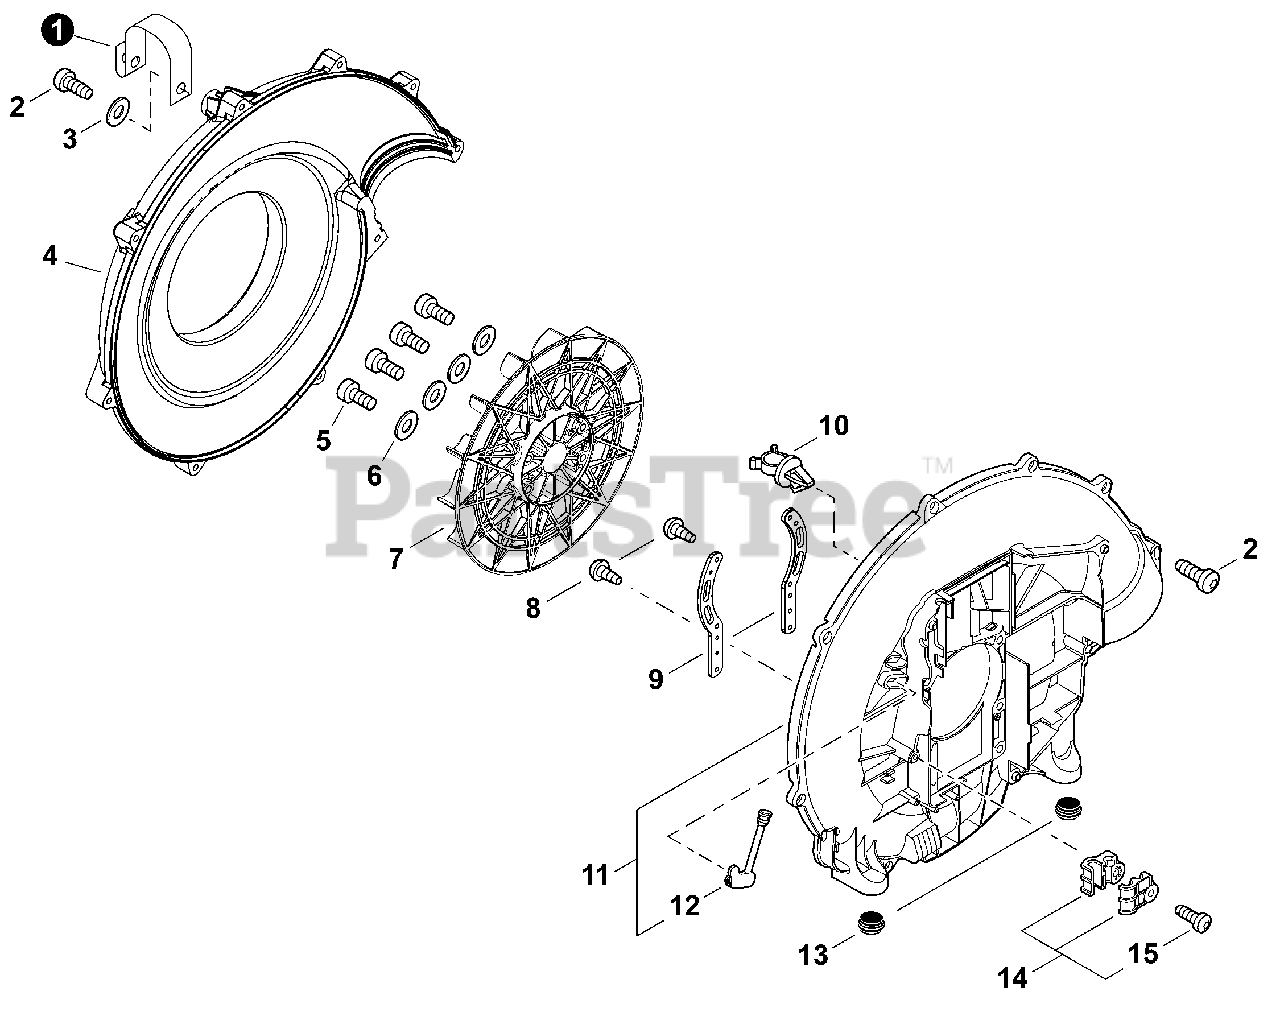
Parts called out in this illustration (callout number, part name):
1	STRAP, SAFETY 1.2×100
2	BOLT, TORX 5×20
3	WASHER 5.5×16×2T
4	COVER, FAN
5	BOLT, TORX 5×30
6	WASHER 5.5×16×2T
7	FAN, BLOWER
8	SCREW TAPPING 3×12
9	BRACKET, ENGINE
10	CLIP, CABLE
11	FAN CASE SET
12	GROMMET
13	CUSHION
14	CABLE HOLDER SET
15	BOLT, TORX 5×25
